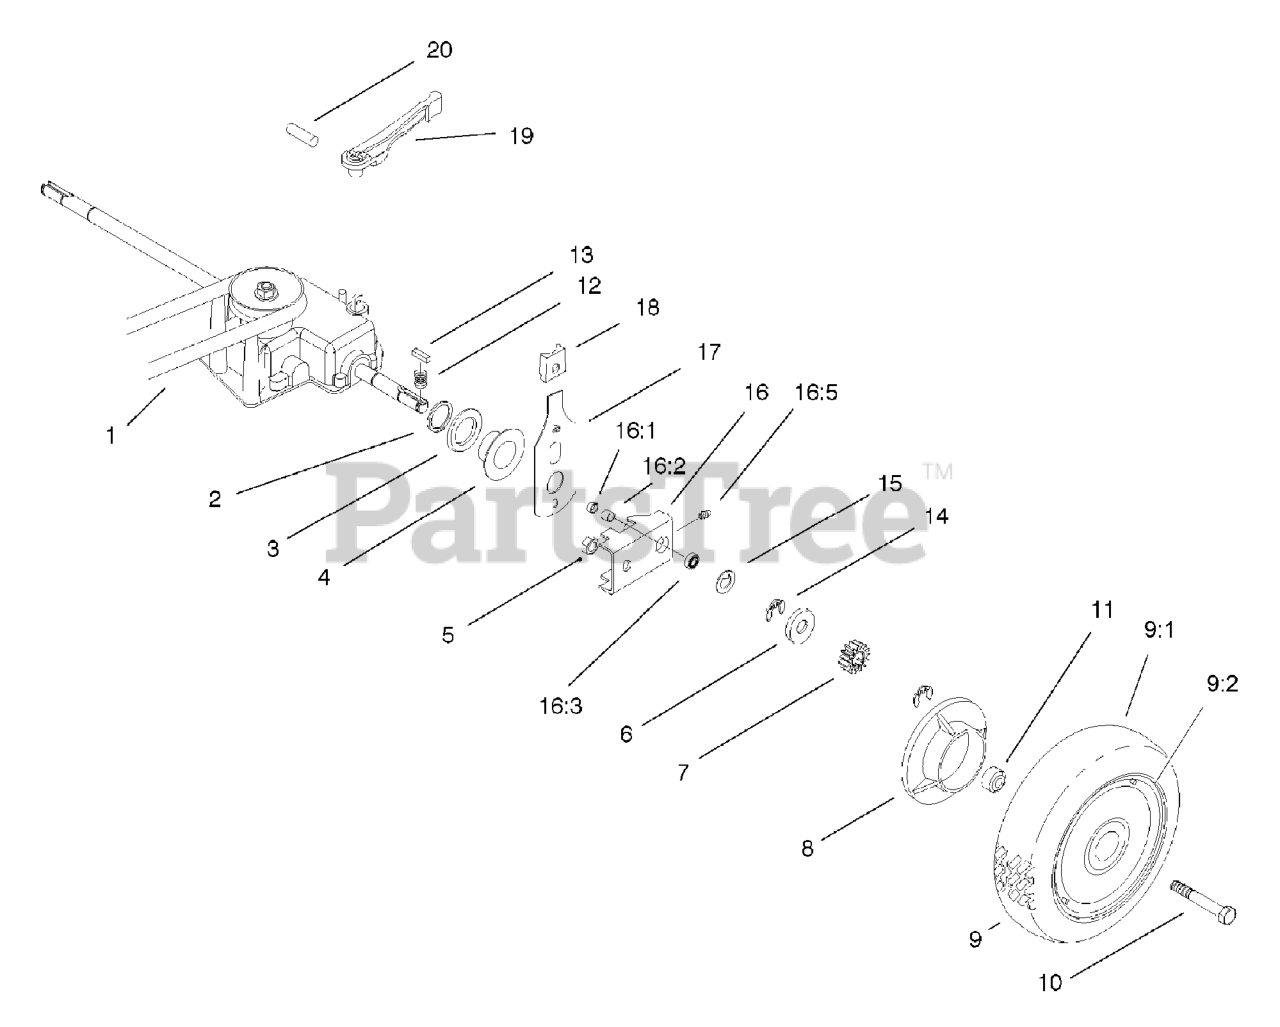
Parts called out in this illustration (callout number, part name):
1	V-BELT
2	RING-RETAINING
4	CAP-END
5	NUT-LOCK, CONE
6	WASHER-THRUST, OUTER
7	GEAR-PINION
8	COVER-WHEEL
9:2	Wheel Asm
10	SCREW-HH
11	SPACER-COVER, WHEEL
12	SPRING-COMPRESSION
14	RING-RETAINING
15	WASHER-THRUST, OUTER
16	PIVOT ARM ASM
16:1	SEAL-OIL
16:3	BEARING-WHEEL
17	REAR SPRING ARM ASM
18	KNOB-ARM
19	LEVER-SHIFT
20	PIN-SPRING
